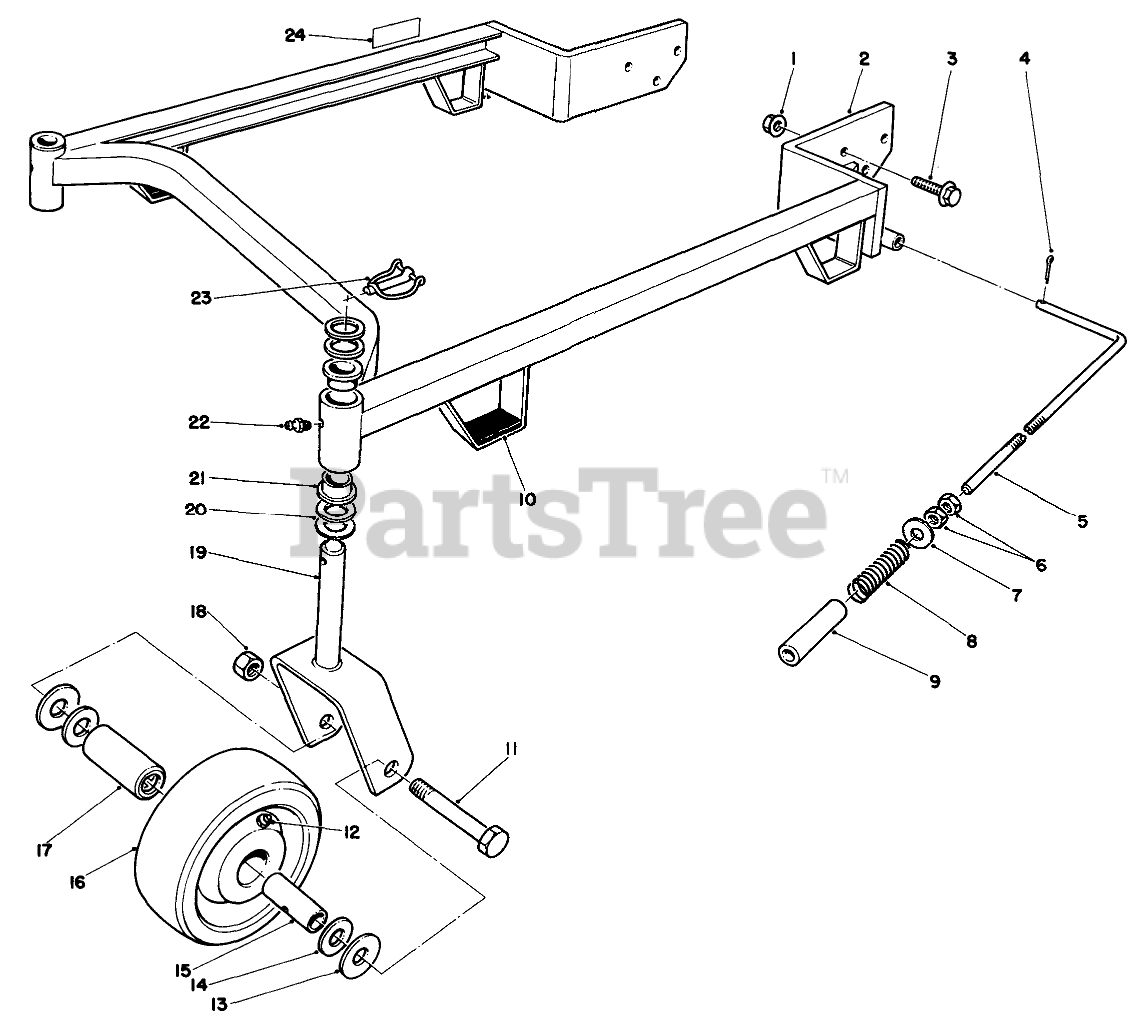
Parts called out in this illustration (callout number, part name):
1	NUT-LOCK, FLANGE
2	Suspension Frame (Incl. Ref. #21)
3	SCREW-HHF
4	PIN-COTTER
5	ADJUSTING SHAFT
6	NUT-JAM
7	WASHER
8	SPRING-COMPRESSION
9	SLEEVE-TUBE, 36 INCH
10	Pad-Rubber
11	SCREW-HH
12	FITTING-GREASE
13	THRUST WASHER
14	BEARING RETAINER
15	SPANNER BUSHING
16	WHEEL
17	ROLLER BEARING
18	NUT-HEX
19	FORK-Castor
20	WASHER-THRUST
21	Bushing
22	FITTING-GREASE
23	PIN-LYNCH
24	DECAL-CAUTION, DEFLECTOR
